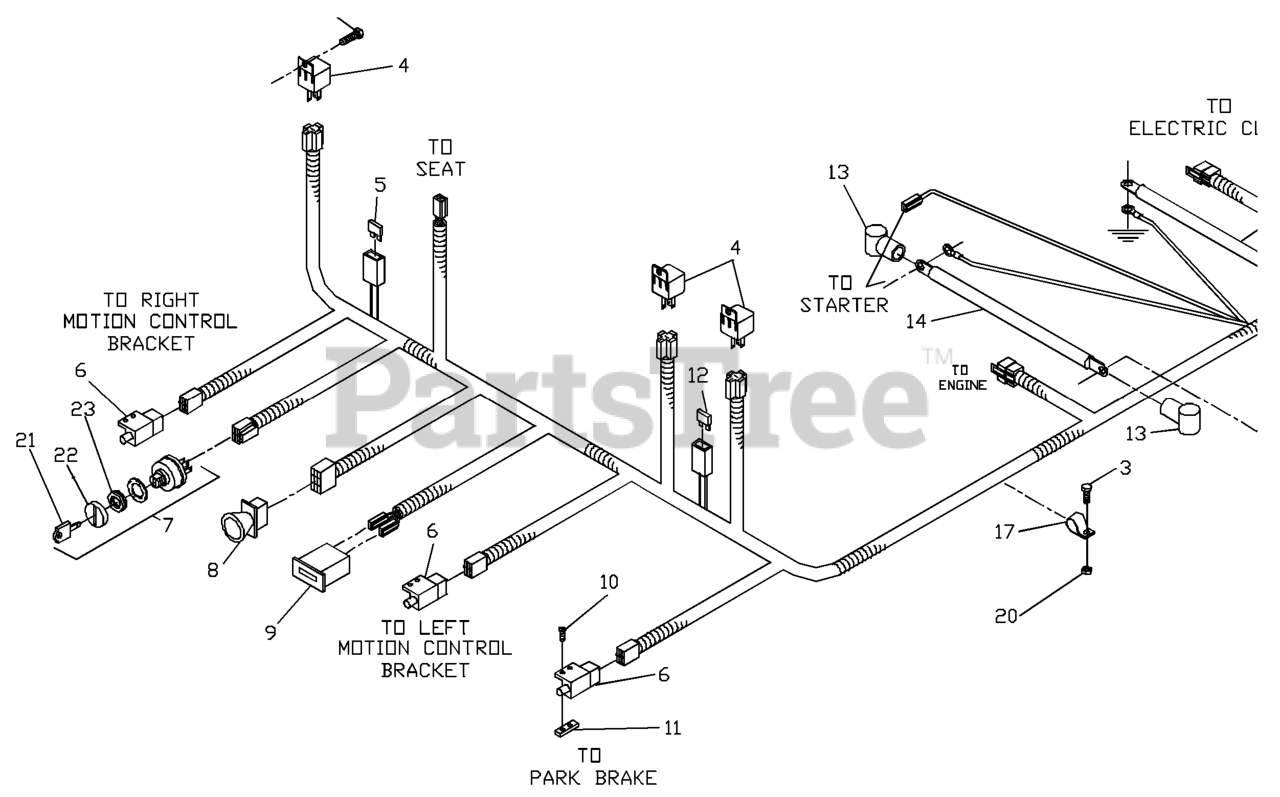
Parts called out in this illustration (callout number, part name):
1	WIRING HARNESS-KOH GEN I
2	SCREW #10 X 1/2 SELF TAPPING
3	HCS 1/4C X 3/4 HCS
5	FUSE, 7.5 AMP 32 VOLT ATO
6	SWITCH, INTERLOCK
7	IGNITION SWITCH KIT
8	RP.SWITCH, BLADE
9	HOUR METER
10	SCREW #10-24 X 5/8
11	TAPPED PLATE
12	FUSE, 20 AMP 32 VOLT ATO
14	CABLE POSITIVE
15	CABLE-NEGATIVE
16	BATTERY, 12 V 330 AMP
18	NUT 5/16C CENTERLOCK
19	SCREW 5/16C X 1 HEX CAP
20	NUT 1/4C CENTERLOCK
21	KEY-PADDED
22	DNO IGNITION NUT
23	CAP IGNITION NUT
